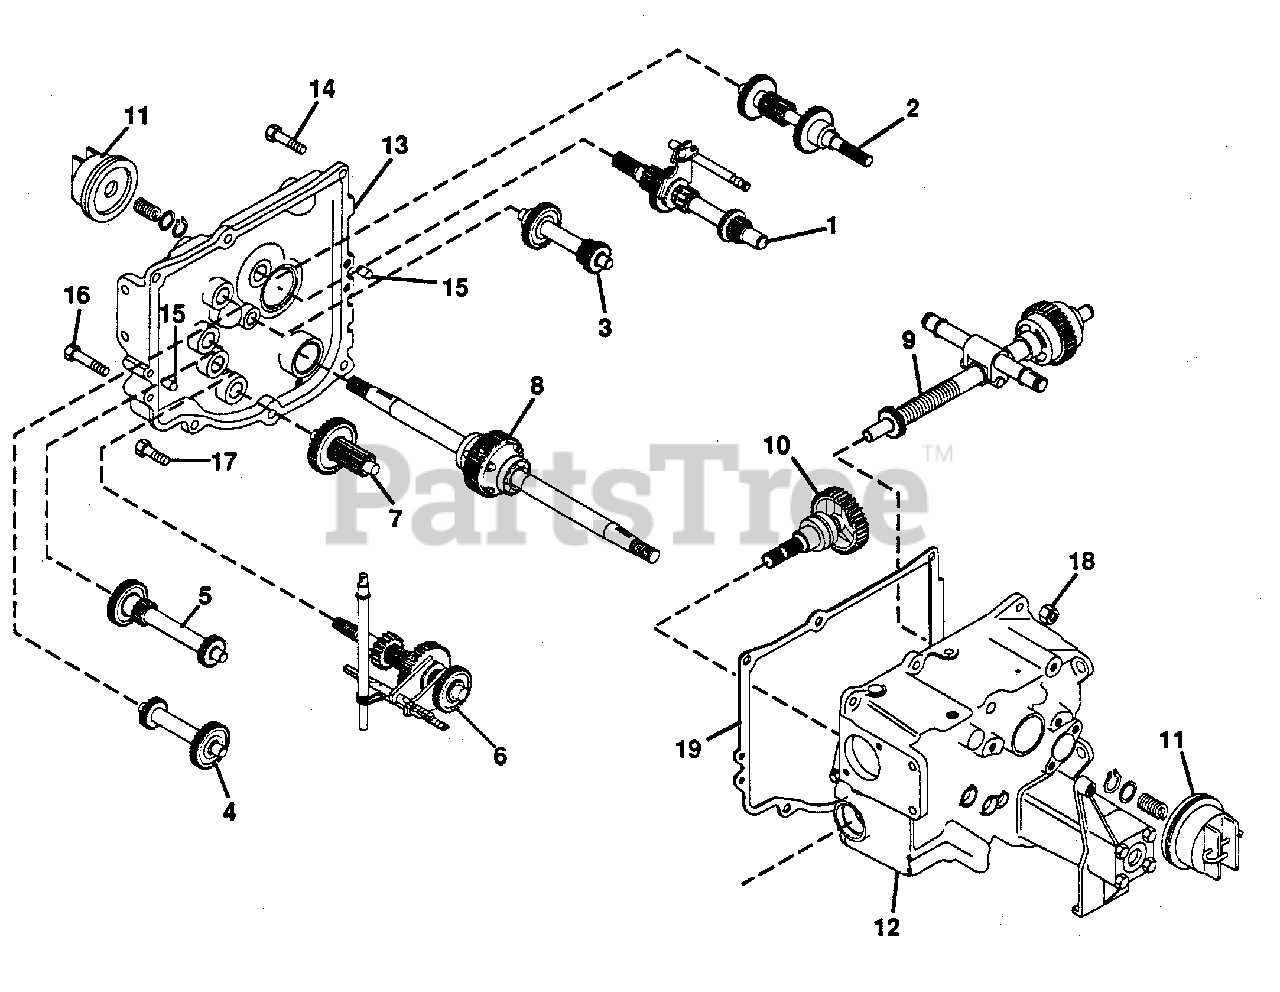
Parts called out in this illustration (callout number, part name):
1	NO. 1 SHAFT, FORWARD CLUTCH
2	NO. 2 SHAFT, REVERSE CLUTCH
3	NO. 3 SHAFT, 3RD AND 4TH GEAR
4	NO. 4 SHAFT, IDLER
5	NO. 5 SHAFT, 1ST AND 2ND GEAR
6	NO. 6 SHAFT, BRAKE-SLIDING GEAR
7	NO. 7 SHAFT, PINION-FINAL DRIVE
8	NO. 8 SHAFT, DIFFERENTIAL ASM.
9	NO. 9 SHAFT, PTO CLUTCH
10	NO. 10 SHAFT, PTO DRIVE ASM.
11	NO. 11, FWD-REV CLUTCH ASM.
12	NO. 12, TRANSMISSION CASE ASM.
13	NO. 13, TRANSMISSION COVER ASM.
14	BOLT, HEX 3/8-16X2.00
15	PIN, DOWEL .375X.625
16	BOLT, HEX 3/8-16X2.25
17	BOLT, HEX 3/8-16X1.50
18	NUT, LOCK 3/8-16
19	GASKET, TRANSMISSION COVER
